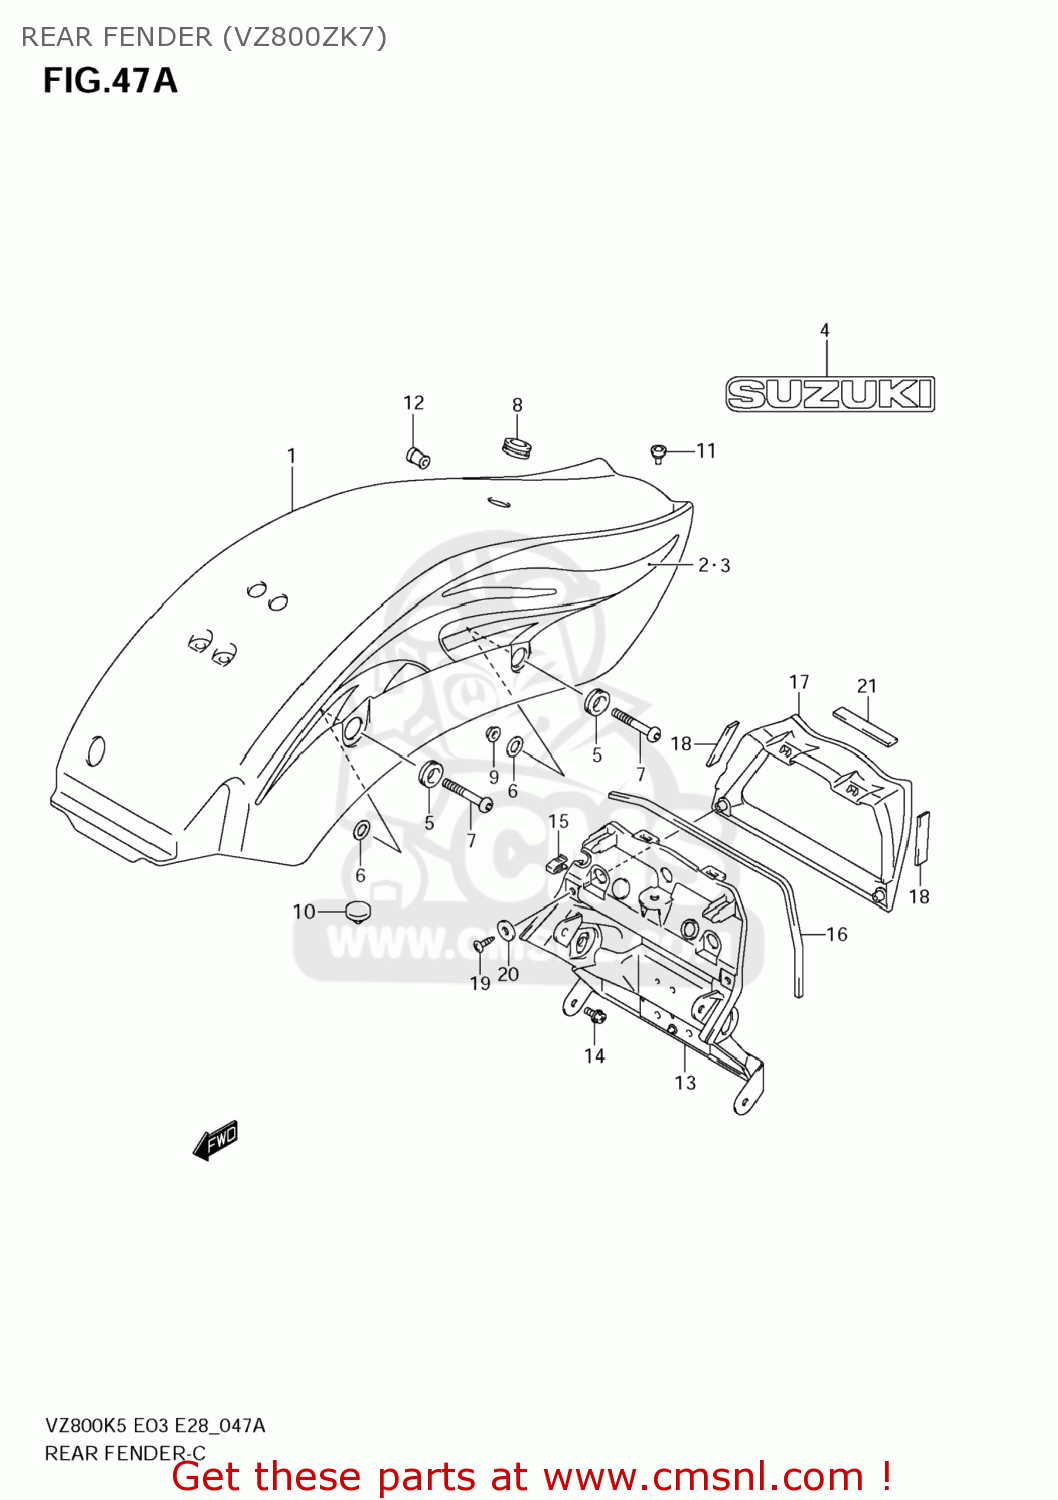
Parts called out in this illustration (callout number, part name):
1	FENDER, REAR FRONT (GRAY)
2	TAPE,RR FENDER,R
3	TAPE,RR FENDER,L
4	EMBLEM,SUZUKI
5	CUSHION,FRAME COVER UPR RR
6	WASHER(15.5X26X2.3)
7	BOLT,RR FENDER
8	CUSHION
9	NUT
10	CUSHION,RR FENDER UPR NO.1
11	CUSHION
12	CUSHION,GRIP
13	FENDER,REAR,RR
14	BOLT(6X16.5)
15	CLIP
16	CUSHION,RR FENDER RR
17	COVER,RR FENDER RR
18	CUSHION,RR FENDER RR COVER
19	SCREW
20	WASHER
21	CUSHION,RR FENDER RR
